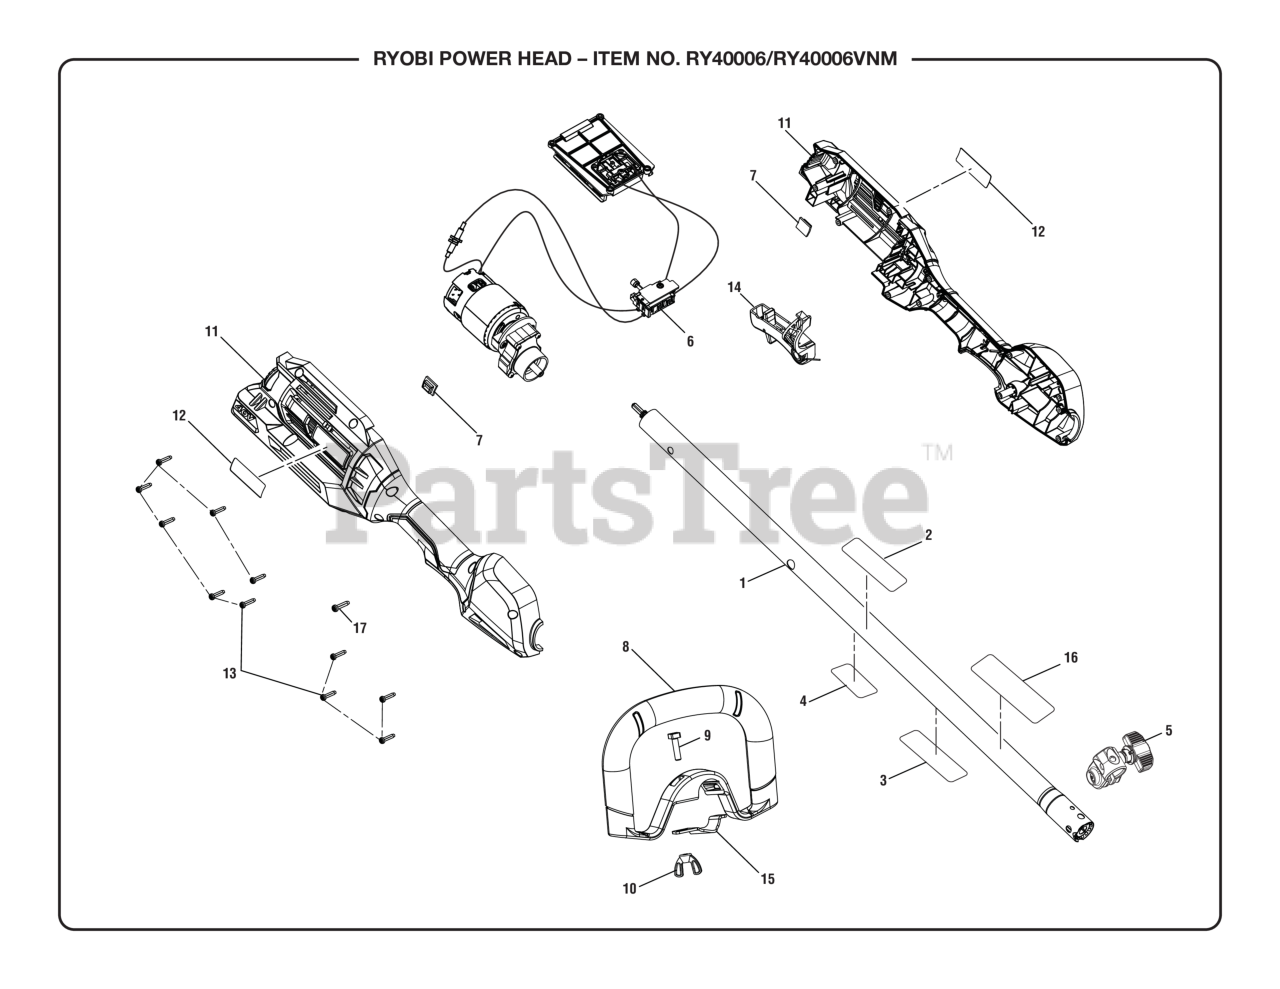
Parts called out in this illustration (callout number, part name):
1	Boom Assembly
2	Warning Icon Label
3	Warning Label (French/Spanish)
4	Data Label
5	Boom Clamp Assembly
6	Motor, Gear Box, Switch & Contact Plate Assembly
7	Rubber Bumper
8	Front Handle Assembly
9	Bolt (1/4-20 x 1 in., Square Hd.)
10	Wing Nut (1/4-20, Plastic)
11	Rear Handle Assembly (Inc. Key No. 12)
12	Logo Label
13	Screw (M4 x 18 mm, T15 Torx Pan Hd.)
14	Switch Trigger Assembly
15	Front Handle Clamp
16	Attachment Label
17	Screw (M3.5 x 16 mm, T10 Torx Pan Hd.)
